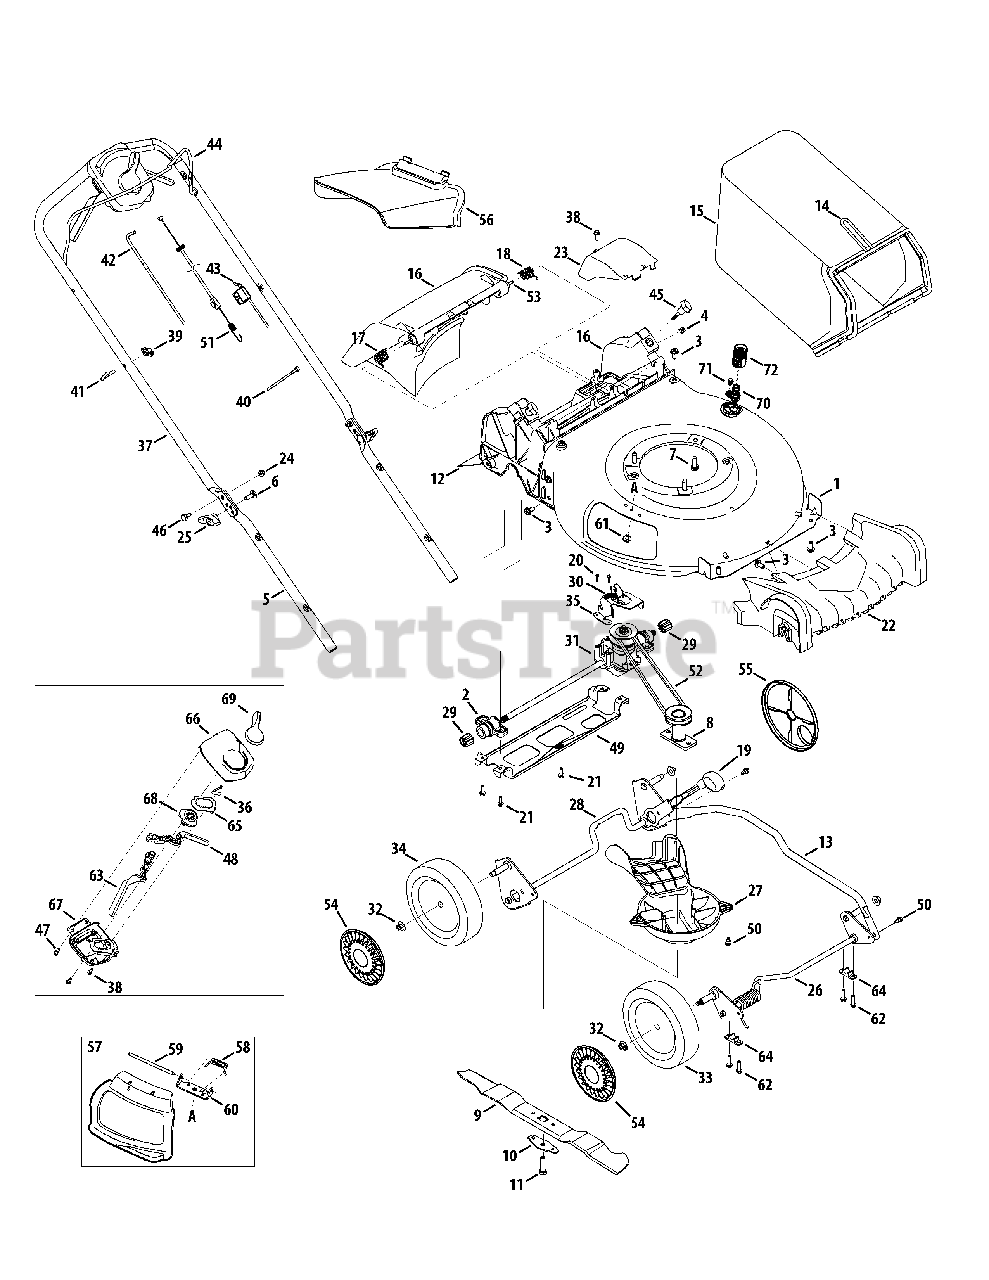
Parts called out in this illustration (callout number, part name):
1	Deck , 21"
2	Bearing Assembly
3	Screw, 5/16-14 x .750
4	Nut, Sq., 1/4-20
5	Lower Handle
6	Carriage Screw ,5/16-18
7	Screw, 3/8-16 x 1.00
8	Blade Adapter
9	Mulching Blade
10	Blade Bell Support
11	Screw, 3/8-24 x 1.50
12	Trailing Shield
14	Grass Catcher Frame
15	Grass Bag
16	Rear Discharge Door Assembly
17	Torsion Spring - RH
18	Torsion Spring - LH
19	Adjustment Lever Knob
20	Screw, .159 x .43 Hex Washer
21	Screw, 1/4-15 x 1.25
22	Front Cover
23	Transmission Cover
24	Nut, Flange Lock, 1/4-20
25	Wing Knob
26	Front Axle Assembly
27	Engine Baffle
28	Rear Axle Assembly
29	Spur Gear, 10T
30	Exten. Spring, 2.675
31	Transmission Assembly
32	Flange Lock Nut, 3/8-16
33	Front Wheel
34	Rear Wheel
35	Transmission Bracket
36	Spring
37	Upper Handle
38	Screw, 1/4-15 x .750
40	Cable Tie
41	Rope Guide
42	Drive Cable
43	Control Cable
44	Blade Control
45	Wing Nut
46	Sldr. Screw, .375 x .126 x 1/4-20
47	Scr., Shldr, 1/4-15 x .970
48	Control Lever LH
49	Rear Support Bracket
50	Scr., Shldr., 1/4-20 x .50
51	Speed Adjustment Cable
52	V-Belt
53	Pivot Rod
54	Hubcap, Grey
55	Wheel Dust Cover
56	Side Discharge Chute
57	Mulch Plug (Incl. 58-60)
58	Torsion Spring
59	Hinge Pin
60	Chute Deflector Bracket
61	Screw, 1/4-20 x .500
62	Screw, 1/4-15 x 1.000
63	Control Lever RH
64	Bushing, Lock, .505 Dia. X .62
65	Cable Adjust Plate
66	Upper Housing
67	Lower Housing
68	Speed Adjust Actuator
69	Speed Select Lever
70	Water Nozzle
71	Scr., Shldr., 1/4-20 x .50
72	Water Nozzle Adapter
